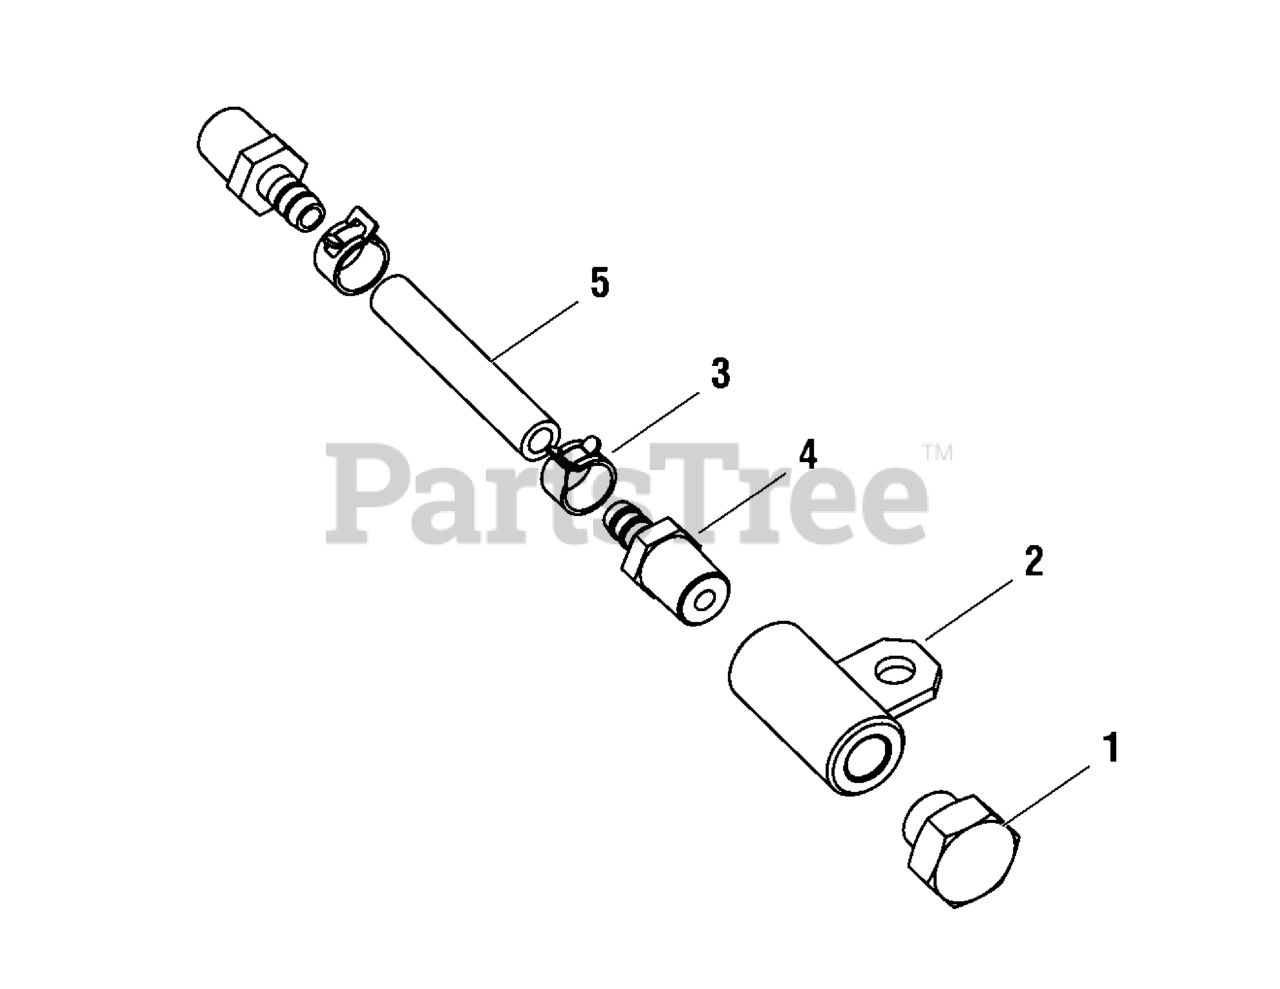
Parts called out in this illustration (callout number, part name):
1	PLUG, Hex Head, M14 x 1-1.5
2	NOZZLE
3	SPRING CLAMP
4	TAPER JOINT
5	OIL PIPE
